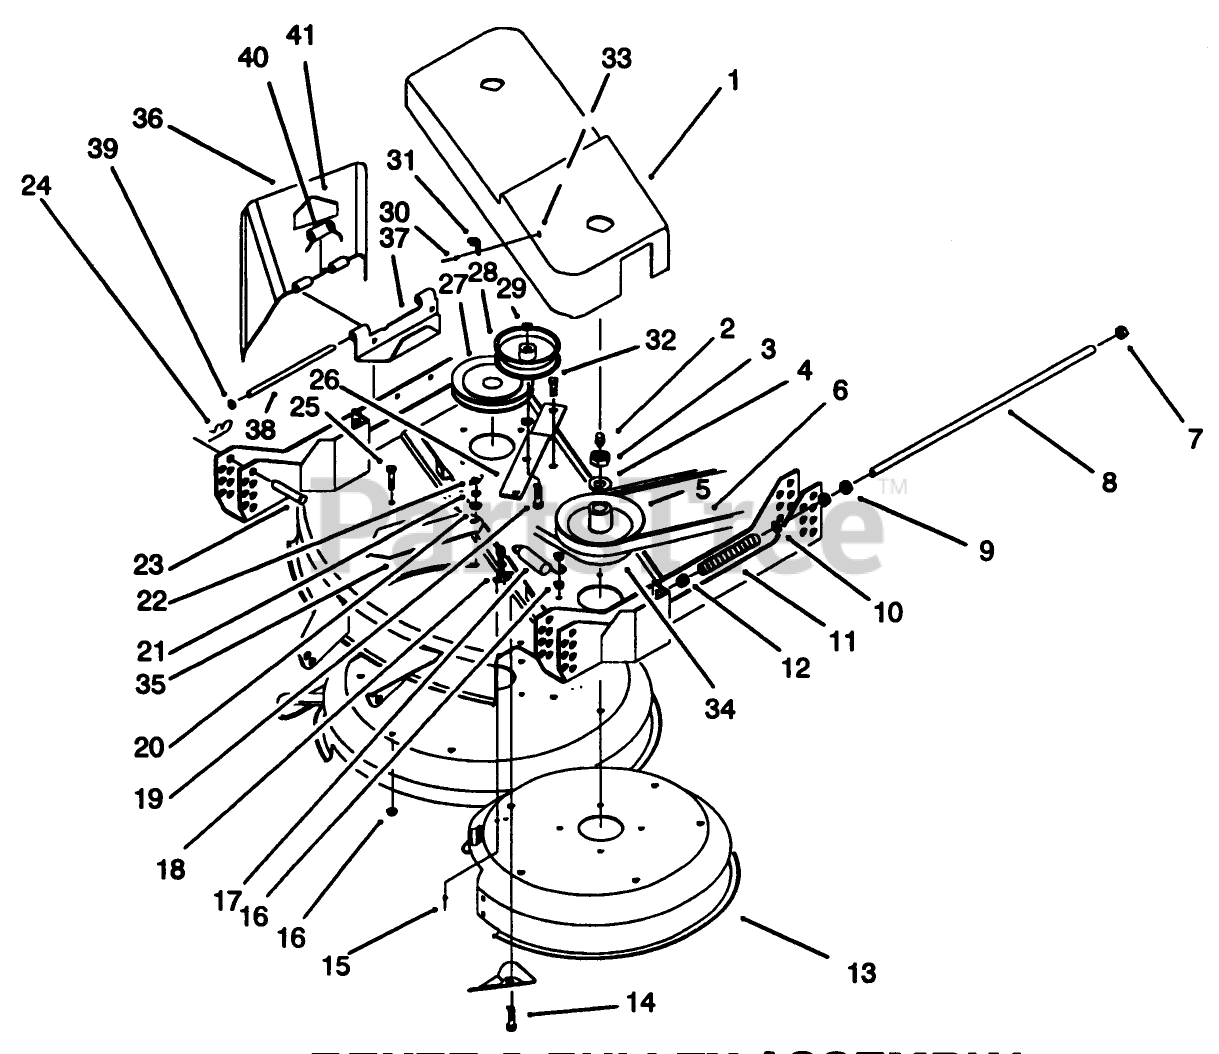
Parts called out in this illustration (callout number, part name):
1	COVER-PULLEY
2	FITTING-GREASE
3	NUT-HEX
4	WASHER
5	PULLEY-CENTER
6	V-BELT, DECK DRIVE
7	NUT-LOCK, NI
8	SHAFT-ADJUSTING
9	NUT-JAM
10	WASHER
11	SPRING
12	BUSHING-FLANGE
13	Deck (Incl. Ref. #1 & 10 on pg. 1)
14	SCREW-HH
15	NUT-LOCK, NI
16	NUT-LOCK, NI
17	SPRING-EXTENSION, DECK
18	Latch Assembly (Incl. Ref. #31)
19	SCREW-HH
20	WASHER-FLAT
21	WASHER-LOCK
22	NUT-WING
23	PIN-CLEVIS
24	PIN-HAIR
25	SCREW-HH
26	Lever-Idler
27	PULLEY-OUTSIDE
28	PULLEY-IDLER
29	NUT-LOCK, NI
31	KEEPER-LATCH
32	SCREW-SHOULDER
33	WASHER-BACK
34	V-BELT, DECK
35	Cover-Slot
36	Deflector-Discharge
37	Hinge-Deflector
38	PIN-HINGE
39	RING-RETAINING, EXTERNAL
40	SPRING
41	DECAL-DANGER
